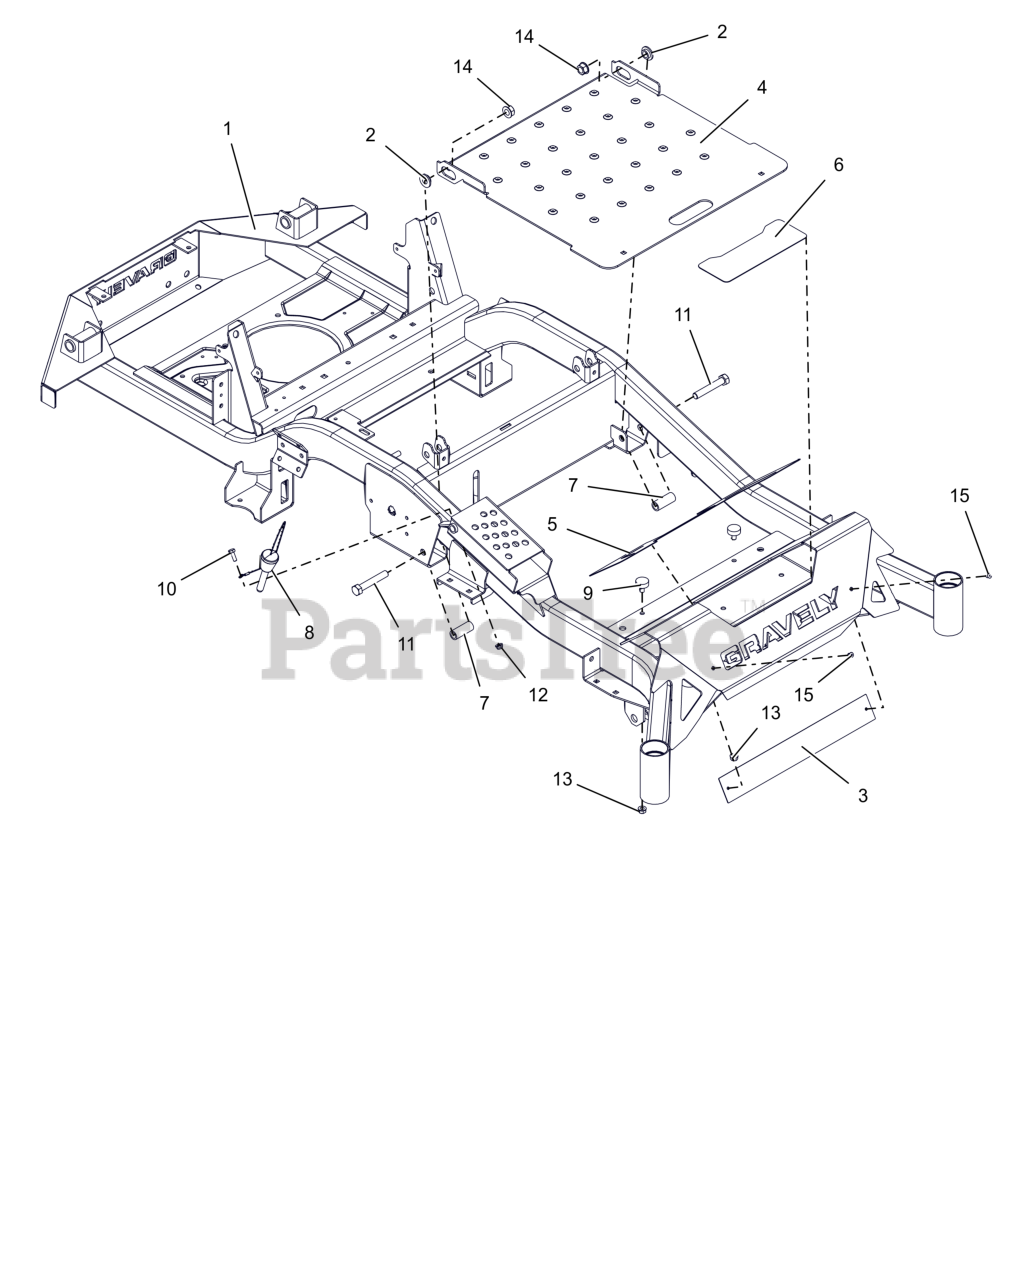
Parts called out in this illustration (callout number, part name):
1	HD 44-52 FRAME W/SAFETY DECALS
2	BSHG-FLG .515X.750X.310X1.120
3	PLATE, BACK FOOT-REST XL
4	KIT,ACCESS PANEL W/DECALS-RED
5	GRIP, FRONT
6	GRIP, STEP
7	SPACER, .515X.75X1.83
8	PIN, MAGNETIC .50X2.50
9	BUMPER, RUBBER
10	BLT, HEX .25-20X.75 G5 ZCC
11	BLT, HEX .50-13X3.00 G5 ZCC
12	NUT,NYL-FLG .25-20 GF ZCC
13	NUT,SPNLK-FLG .31-18 G5 ZCC
14	NUT-LK-TOP-FLG .500-13 GF ZCC
15	RIVET, .1875 AL/AL .126-.250
